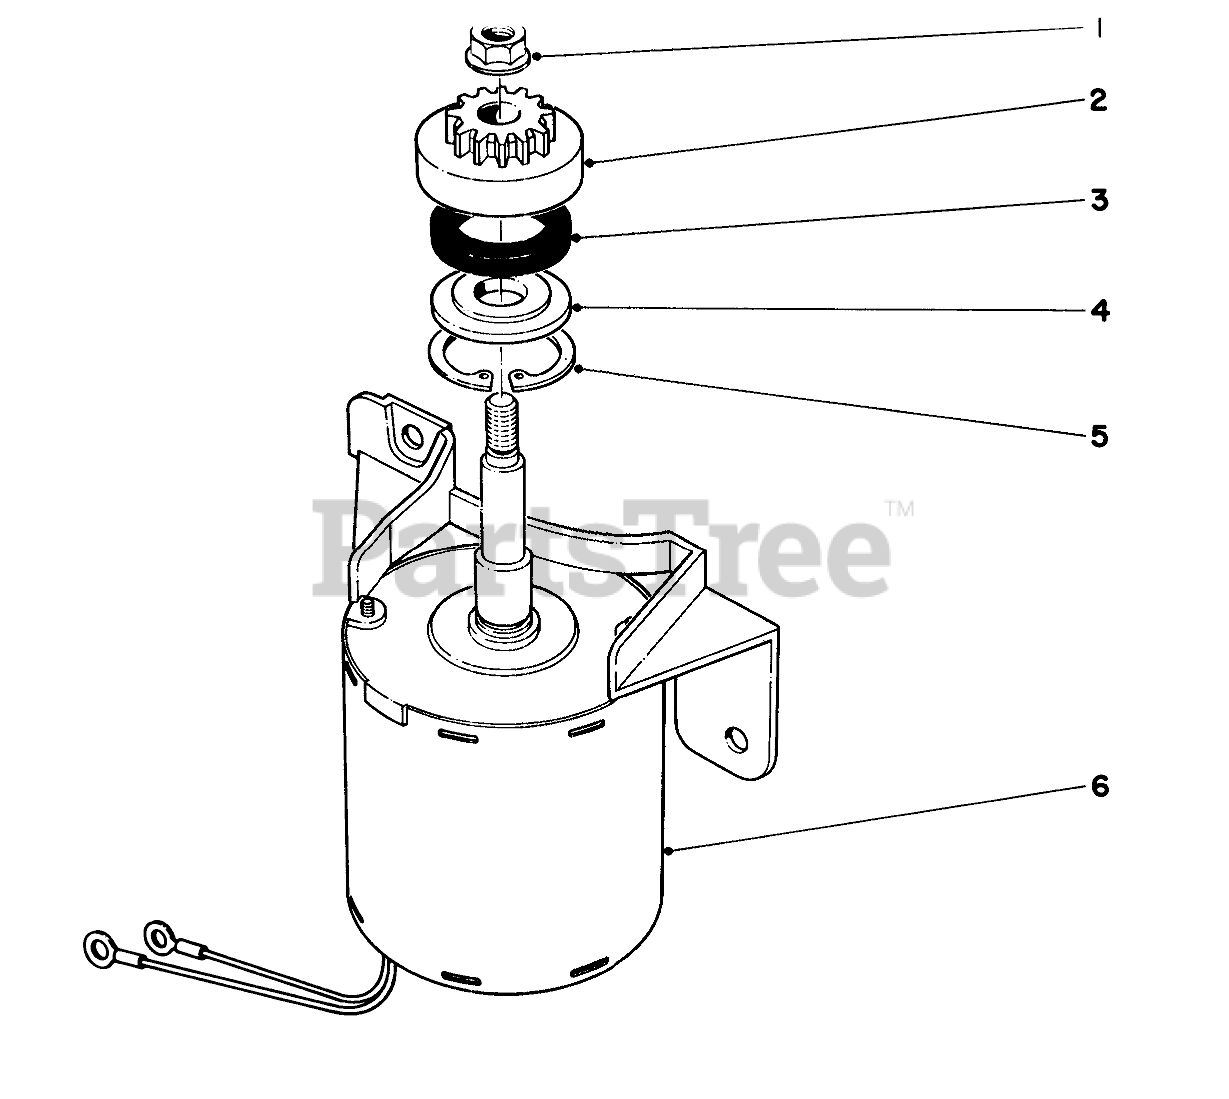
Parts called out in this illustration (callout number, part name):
1	Flange Nut
2	Pinion Assembly
3	RUBBER RING
4	Control Nut
5	Retaining Clip
6	Starter Motor
